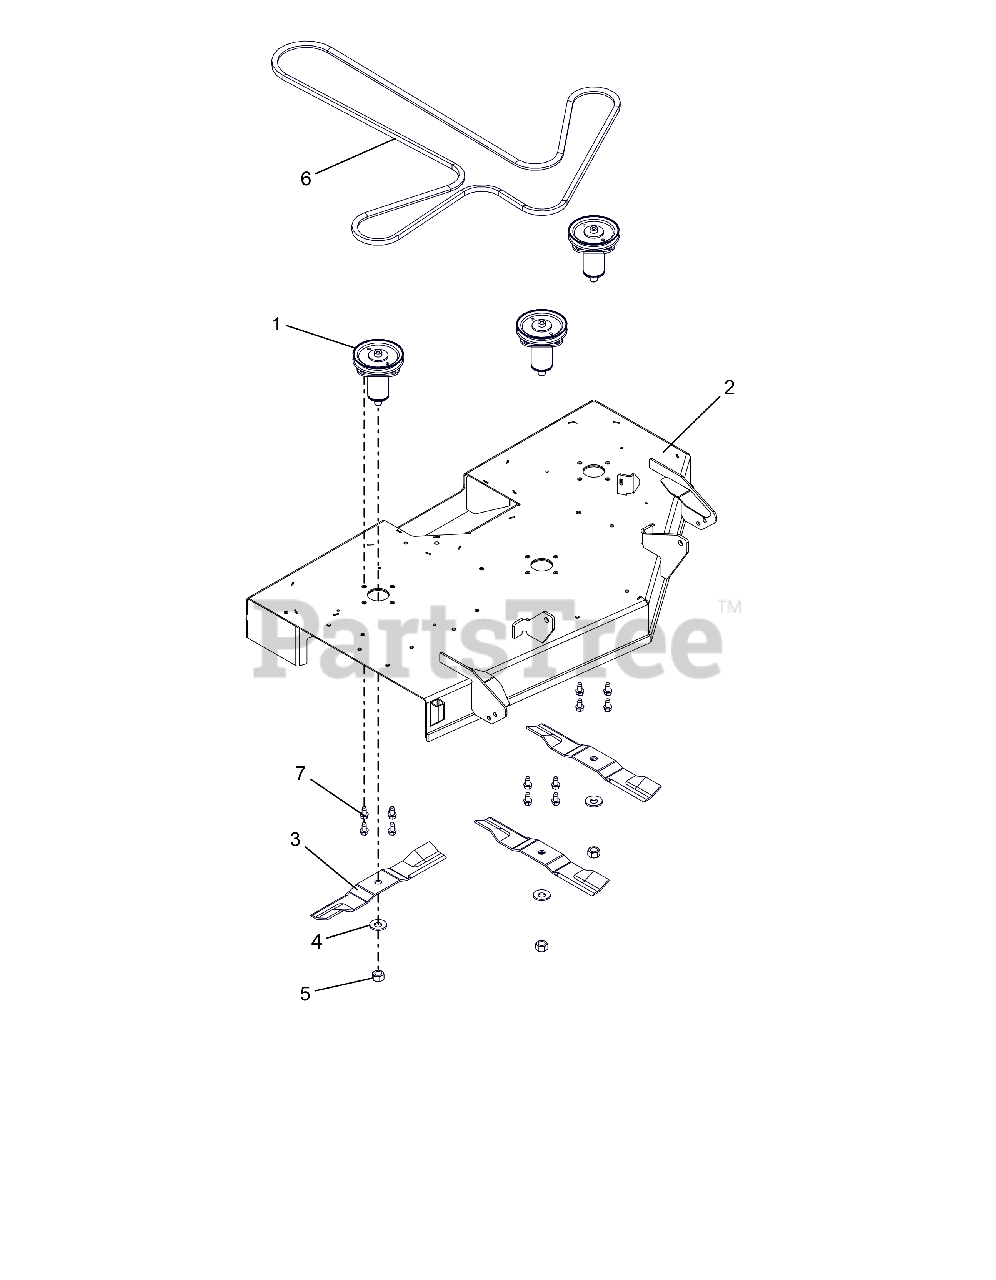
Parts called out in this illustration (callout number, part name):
1	KIT, DECK SPINDLE ASM-IKON-ZTX
2	KIT, 42" ARIENS DECK W/DECALS
3	BLADE, MOWER 15.00"
4	WSHR-BLVL .669X1.535X.138
5	NUT-STD .625-18 ZCC
6	V-BELT, 4L-WRAPPED
7	SCR,TAP .375-16X.75 HWH TR ZCC
